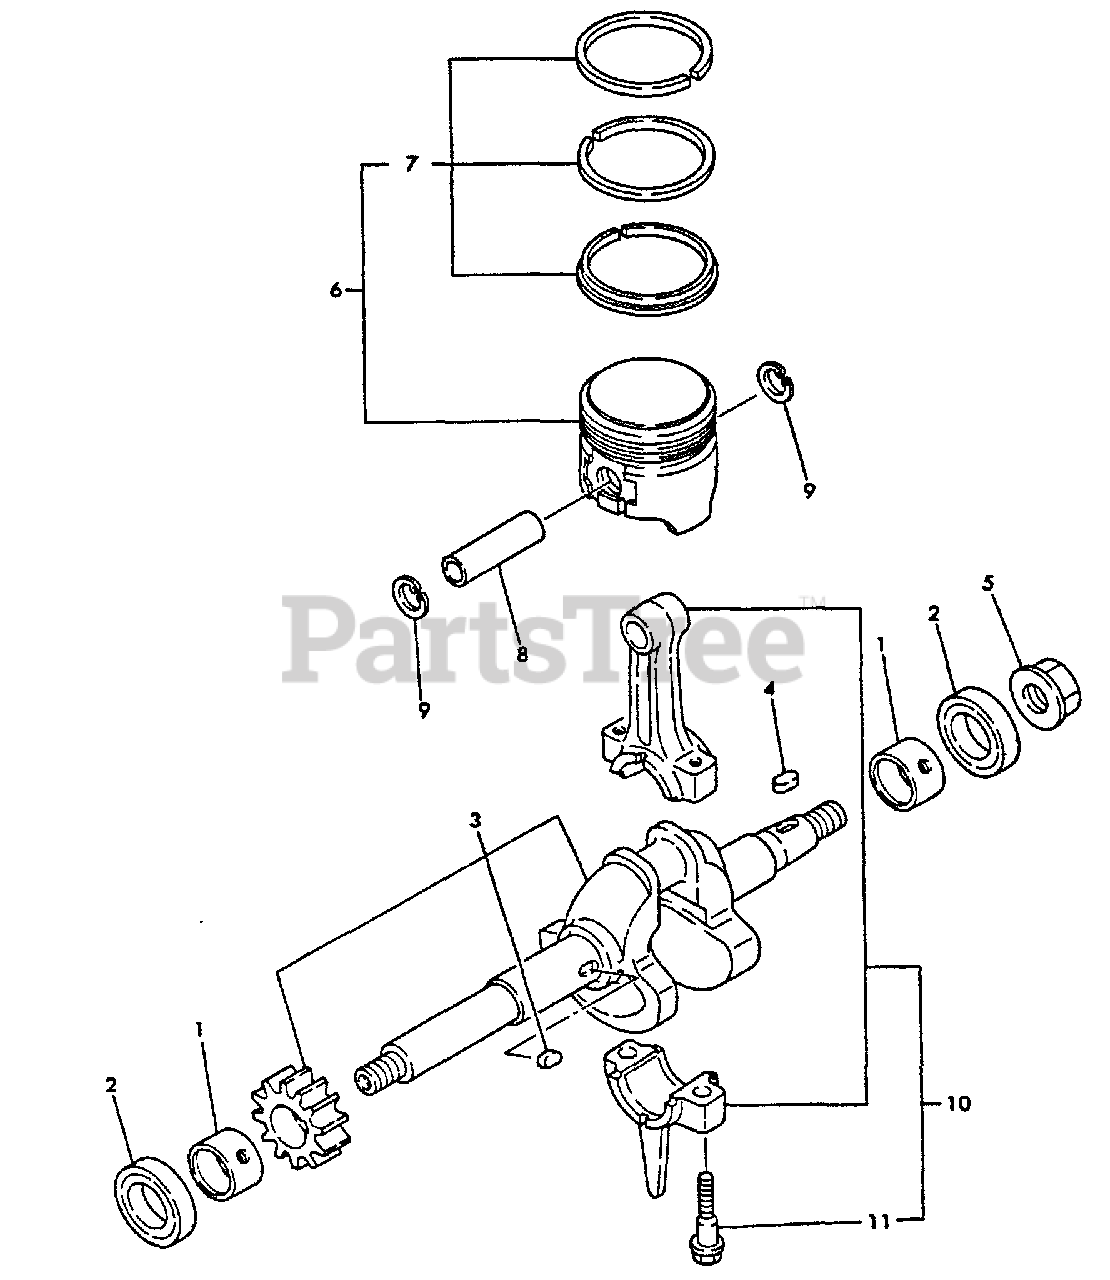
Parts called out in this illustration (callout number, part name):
1	BEARING, MAIN
2	SEAL, OIL
3	CRANKSHAFT ASSY
4	KEY - 4×10
5	NUT - 10 -- FLANGE
6	PISTON ASSY
7	PISTON RING SET
8	PIN, PISTON
9	RING, RETAINING - 11
10	CONNECTING ROD ASSY
11	BOLT, ROD
